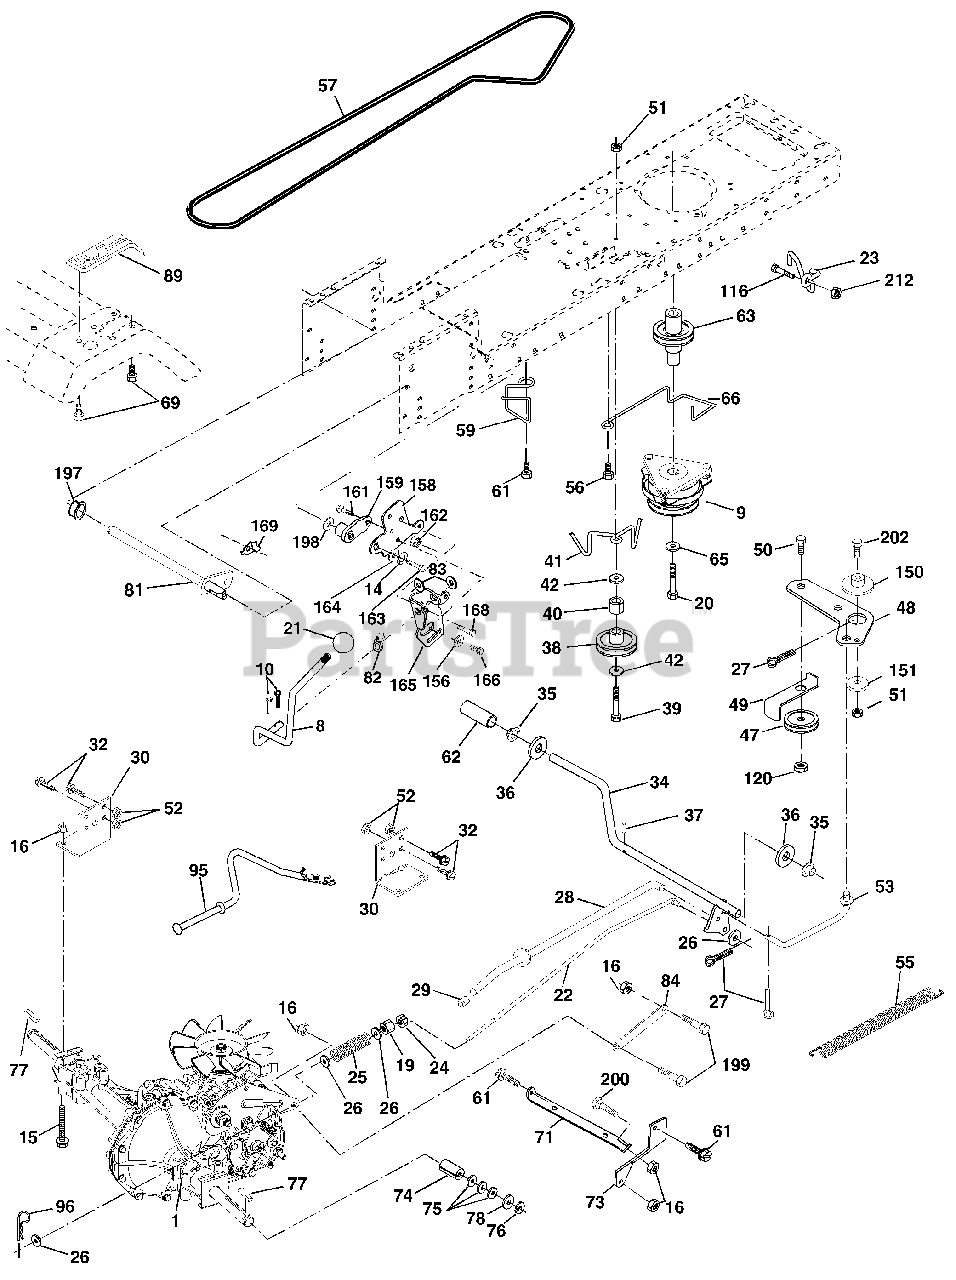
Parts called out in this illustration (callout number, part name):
8	Rod Shift Fender Adjust LT
9	Clutch Elecric
10	Pin Cotter 1/8 x 1 CAD
14	Washer Lock Hvy Helical
15	Bolt Hex 5/16-18 Gr. 5
16	Nut Lock Hex W/Ins. 5/16-18 Unc P
19	Nut Lock Hex W/Ins 3/8-16 Unc
20	Bolt, Hex 7/16-20 x 4-1/4 Ga. 5
21	Knob Deluxe 1/2-13 UNC BLK/BLK
22	Rod, Brake Hydro
23	Bracket Anti-Rot
24	Nut Hex Jam 3/8-16 UNC
25	Spring, Brake Rod
26	Washer
27	Pin Cotter 1/8 x 3/4 CAD.
28	Rod, Parking Brake
29	Cap,Parking Brake
30	Bracket, Transaxle
32	Bolt Hex Hd 5/16-18 Unc x 3/4
34	Shaft, Foot Pedal
35	Bearing, Nylon
37	Pin, Roll
38	Pulley, Idler, Flat
39	Bolt
40	Spacer Split
41	Keeper, Belt Idler
42	Washer 13/32 x 13/16 x 12 Ga
47	Pulley, Idler, V-Groove Plastic
48	Bellcrank Clutch Grnd Drv Stl
49	Retainer, Belt Style Spring
50	Bolt Hex Hd 3/8-16 Unc x 1-1/2
52	Nut Crown Lock 5/16-18
53	Link, Clutch
55	Spring, Return, Clutch
56	Screw 3/8-16 x 1.0
57	V-Belt, Ground Drive
59	Keeper, Center Span
61	Screw 3/8-16 x 3/4
62	Cover, Pedal
63	Pulley, Engine
65	Washer Lock Hvy HLCL Spr 7/16
66	Keeper Belt Engine
69	Screw Hex Wsh Hi-Lo 1/4-1/2 Unc
71	Strap Torque Lh
73	Strap Torque Rh
74	Spacer, Axle
75	Washer 25/32 x 1-1/4 x 16 Ga.
77	Key, Square
78	Washer 25/32 x 1-5/8 x 16 Ga
81	Shaft Asm Cross Tapered
82	Spring Torsion
83	Washer 17/32 x 3/4 x 16 Ga.
84	Link Transaxle
89	Console, Hydro
95	Control Asm. Bypass Hydro
96	Retainer Spring 1" Zinc/Cad
116	Bolt 3/8-16 x 1
120	Nut Lock Flg. 3/8-16
150	Bushing Bellcrank Grd Drive
151	Washer 13/32 x 2 x 10 Ga.
156	Washer Srrted 5/16 ID X 1 X .125
158	Bracket Shift Mount
159	Hub Tapered Flange Shift LT
161	Bolt Rdhd Sqnk 1/4-20 x 3/4 Gr. 5
162	Nut Crownlock 1/4-20 Unc
163	Bolt Hex Fin 1/4-20 Unc x 1 Gr. 5
164	Washer 5/8 x .281 x 10 Ga.
165	Bracket Pivot Lever
166	Screw 5/16-18 x 5/8
168	Bolt Shoulder 5/16-18 x .561
169	Plate Fastening LT
197	Nyliner Snap-In 5/8" ID
198	Washer Nyl 7/8ID x .105 Hyd
199	Bolt Shoulder 5/16-18 Unc
200	Bolt Rdhd Sqnk 5/16-18 Unc x 1
212	Nut 3/8-16
